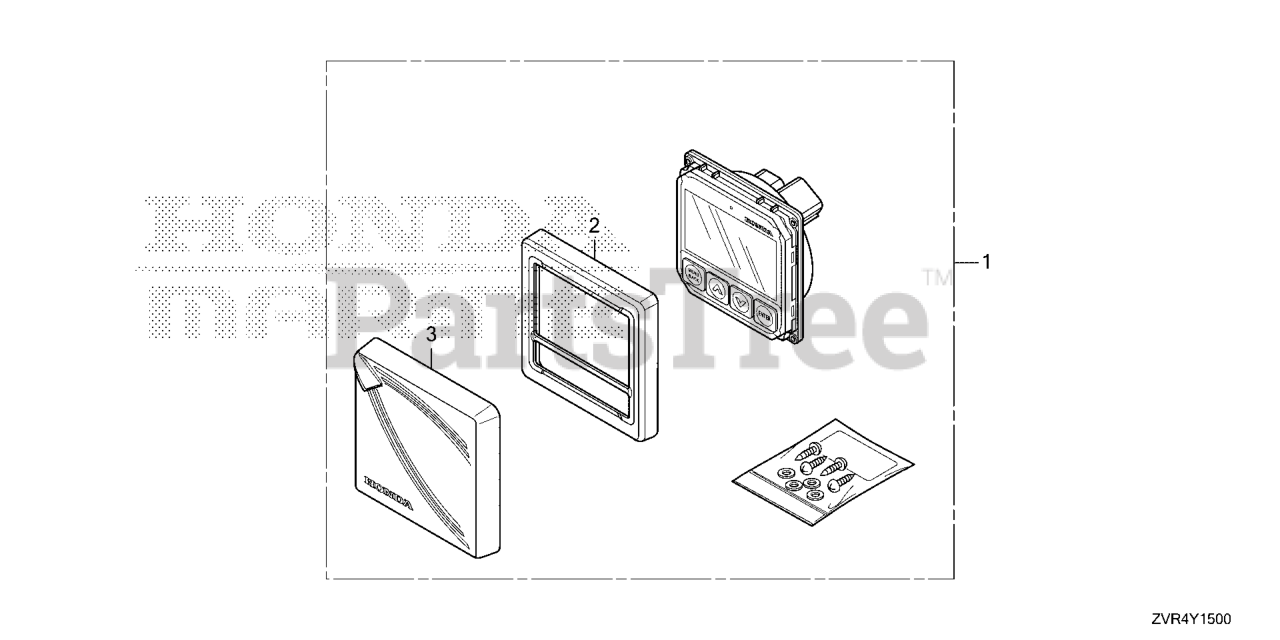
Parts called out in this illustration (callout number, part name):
1	DISPLAY KIT
2	BEZEL, DISPLAY
3	COVER, DISPLAY
